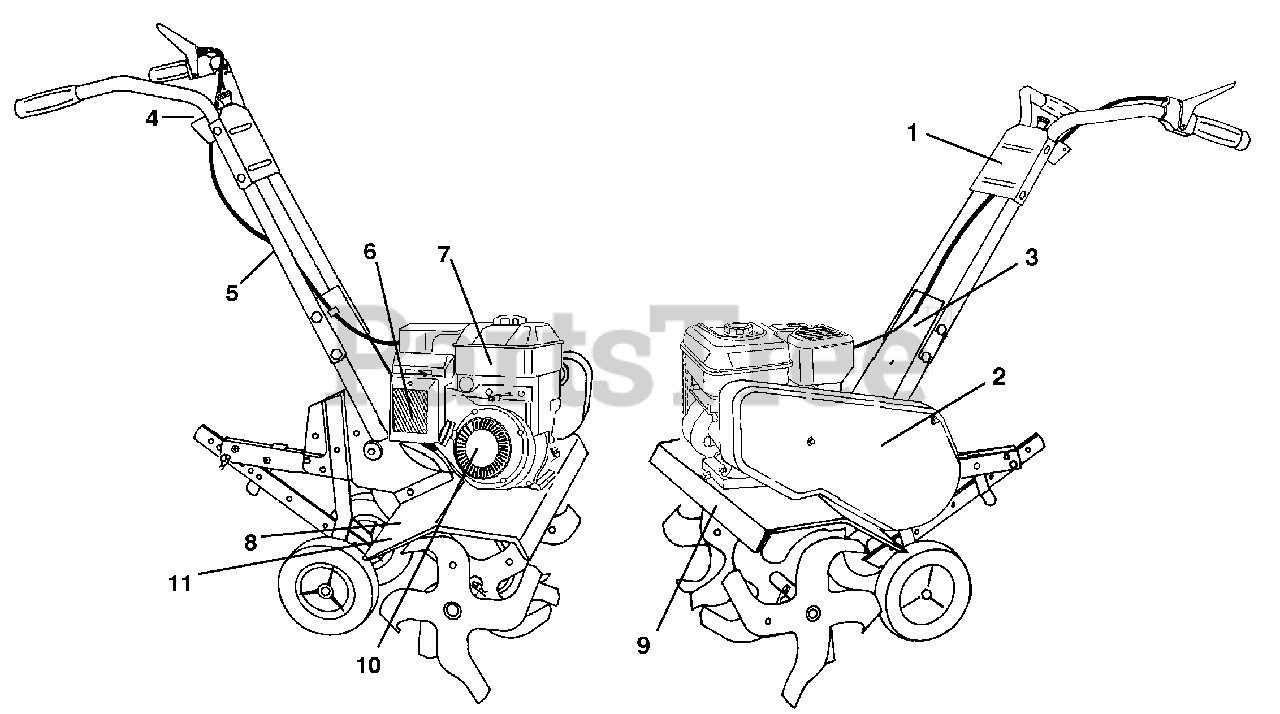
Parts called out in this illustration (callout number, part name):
1	Decal, Poulan Pro
2	Decal, Poulan Pro, 800 Series/26"
3	Decal, Forward and Reverse
4	Decal, Reverse, Tine Control
5	Decal, Hand Placement
6	Decal, Engine
7	Decal, Warning Spark Arrestor
8	Decal, Warning
9	Decal, Heavy Duty
10	Decal, Rewind Starter
11	Decal, Warning, Rotating Tines
11	Manual, Operator's, English/French
11	Manual, Repair Parts
